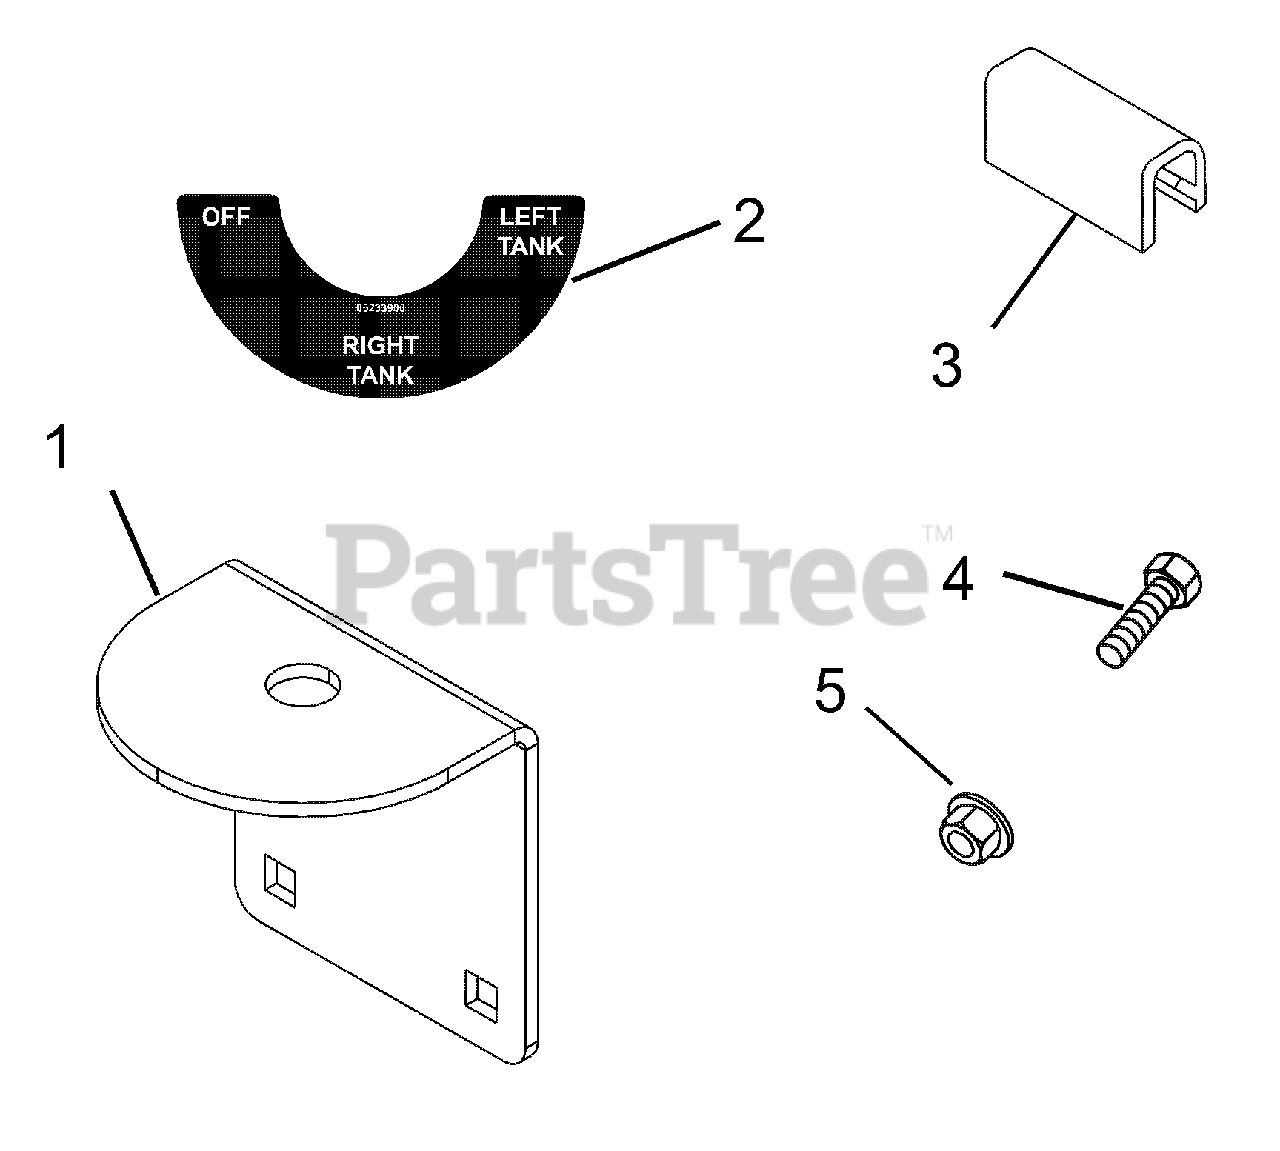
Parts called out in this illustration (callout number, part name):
1	Fuel Valve Mounting Bracket
2	Decal, Fuel Valve
3	Cowl Strip, 1.75" LG
4	Bolt, Hex .31-18 x .75
5	Nut, Locking Top Flange
